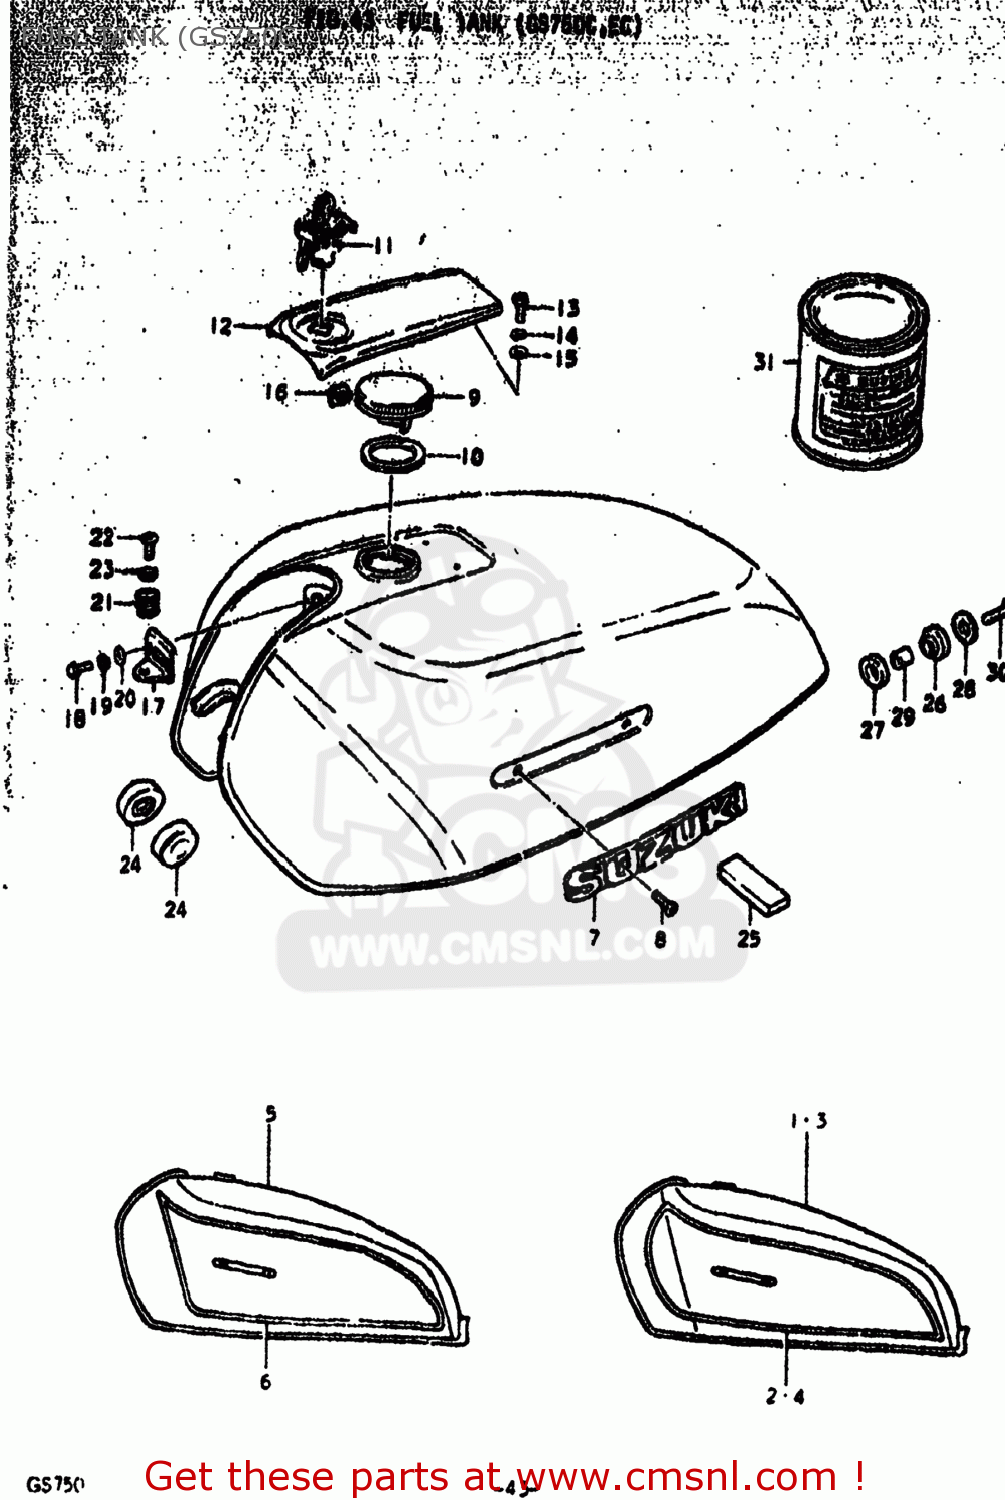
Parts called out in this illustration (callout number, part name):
1	TANK ASSEMBLY,FUEL
3	TANK ASSEMBLY,FUEL
5	TANK ASSEMBLY,FUEL
7	EMBLEM,FUEL TANK
8	SCREW
9	CAP,FUEL TANK
10	GASKET (NAS)
11	LOCK,FUEL TANK FR COVER
12	COVER,FUEL TANK
13	BOLT
14	LOCK WASHER
15	WASHER
16	CUSHION,FUEL TANK FR COVER
17	HOLDER,FUEL TANK FRONT COVER
18	BOLT
19	LOCK WASHER
20	WASHER
21	SPRING
22	SCREW
23	LOCK WASHER
24	CUSHION
25	CUSHION
26	CUSHION
27	CUSHION
28	WASHER (8.5X29X1.6)
29	SPACER(8.1X11X5.4)
30	BOLT (8X30)
31	PAINT,BLACK
